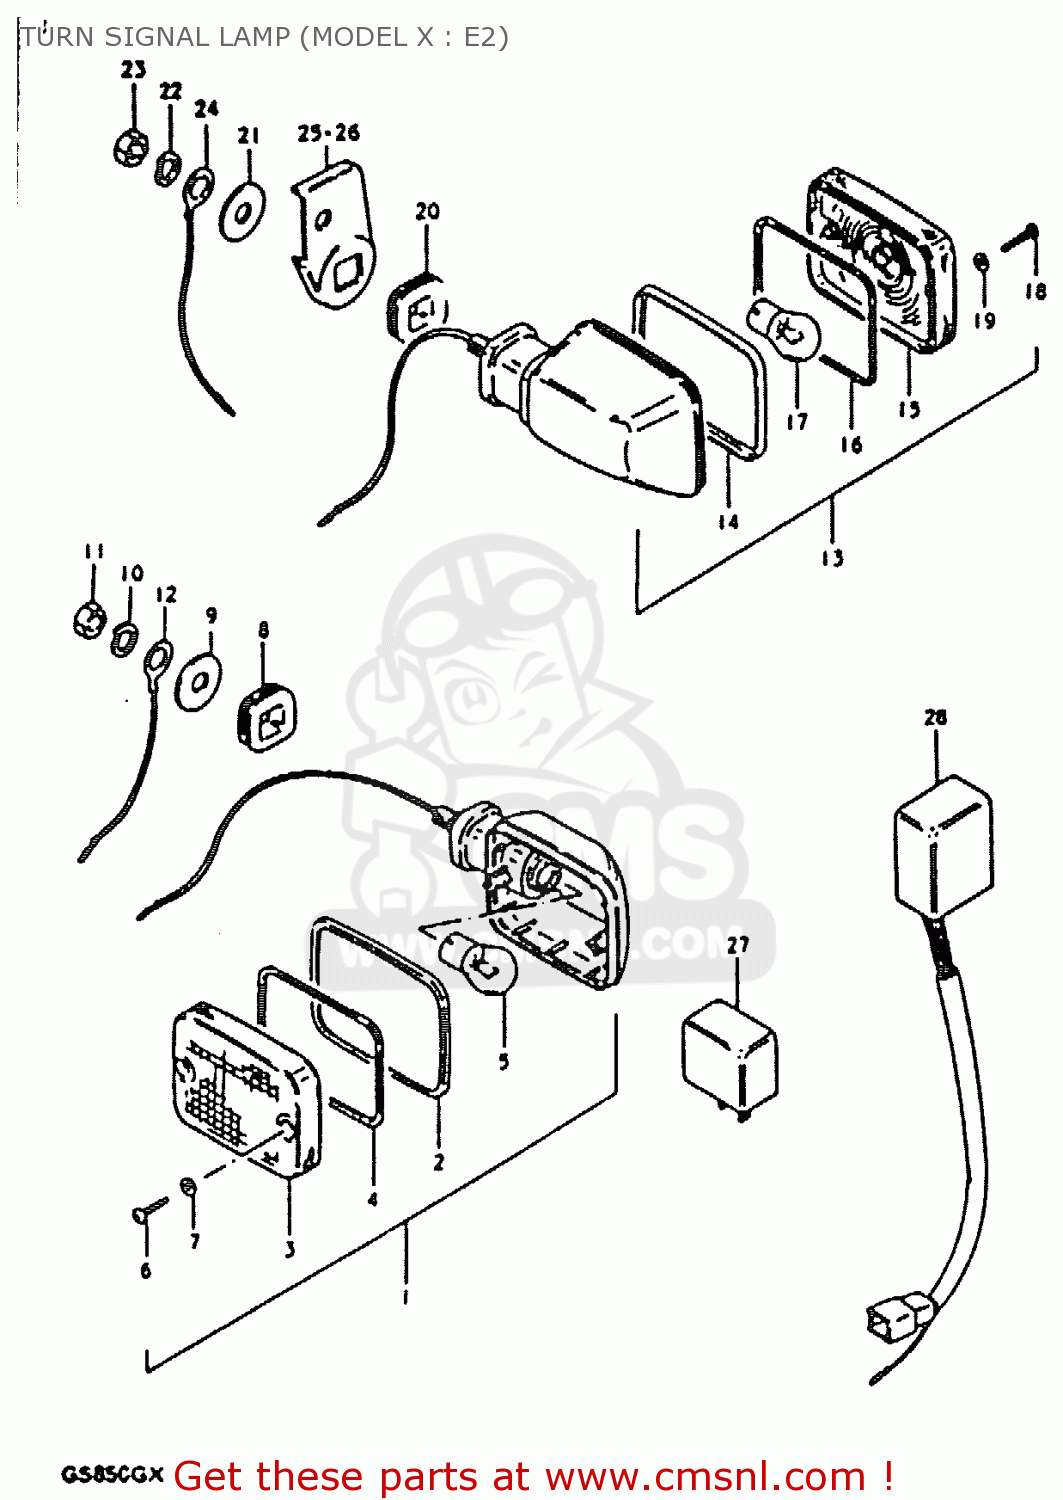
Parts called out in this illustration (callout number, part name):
1	LAMP, REAR TURN SIGNAL
2	RIM
3	LENS
4	GASKET (NAS)
5	BULB 12V 21W
6	SCREW
7	GASKET (NAS)
8	CUSHION
9	WASHER (10.5X30X2.3)
10	LOCK WASHER
11	NUT
12	LEAD WIRE,EARTH
13	LAMP, REAR TURN SIGNAL
14	RIM
15	LENS
16	GASKET (NAS)
17	BULB 12V 21W
18	SCREW
19	GASKET (NAS)
20	CUSHION
21	WASHER (10.5X30X2.3)
22	LOCK WASHER
23	NUT
24	LEAD WIRE,EARTH
25	BRACKET,RR TURNSIGNAL LAMP,R
26	BRACKET,RR TURNSIGNAL LAMP,L
27	RELAY ASSY,TURNSIGNAL
28	UNIT,TURN SIGNAL CONTROL
